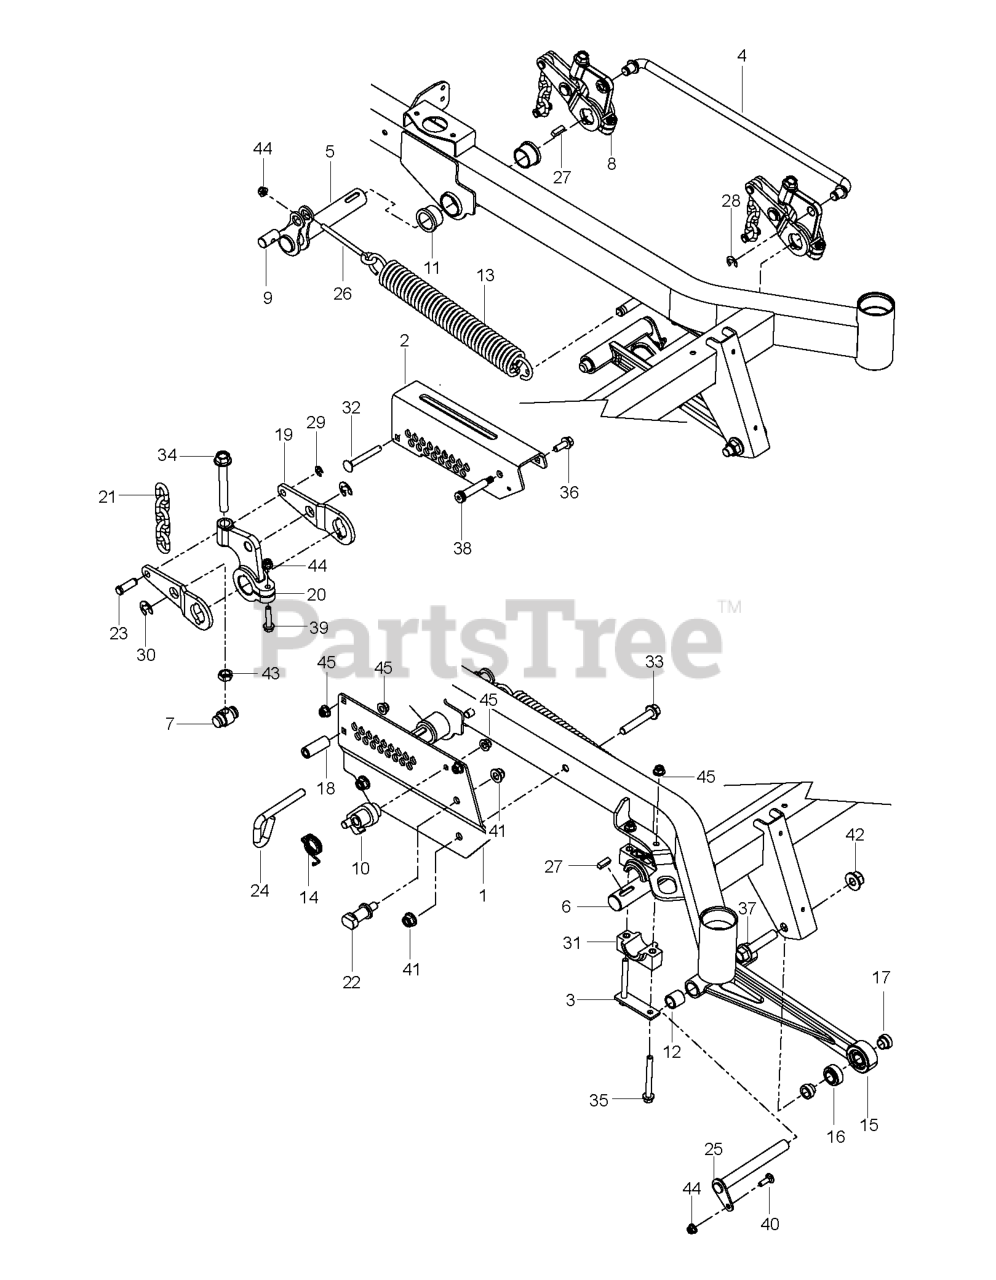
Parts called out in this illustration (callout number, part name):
1	PLATE INNER HEIGHT SNAPPER RED
2	PLATE OUTER HEIGHT SNAPPER RED
3	PLATE, PILLOW BLACK
4	ROD, LIFT
5	SHAFT, RR LIFT
6	SHAFT, LIFT, FT
7	SHAFT, LIFT TRUNION WSL
8	ASSEMBLY, DECK LIFT CRANK
9	PIVOT, SPRING
10	LATCH, TRANSPORT WLDMT
11	BUSHING, FLANGE 1.25 X 1.0
12	BUSHING, SLEEVE 3/4 X 1.0
13	SPRING, EXTENSION
14	SPRING, TORSION
15	ASSEMBLY, STRUT
16	BALL JOINT, 3/4" SWIVEL
17	SPACER, STRUT
18	SPACER, HEIGHT PLATE
20	ARM, CAST LIFT
21	LIFT CHAIN
22	GUIDE, HEIGHT BAR
23	PIN, 7/16 CLEVIS
24	PIN, HEIGHT
25	PIN, STRUT
26	EYE BOLT 4.5`
27	KEY, 5/16 SQ X 1.0
28	E-RING 5/8
29	RING, E, 7/16
30	E RING 3/4
31	BLOCK, PILLOW
32	3/8-16 X 3` CARR BOLT
33	HFFS 1/2-13 X 3 GD 5 ZD
34	HHFS 1/2-13 X 4 GR 5
35	HHFS 3/8-16 X 3.5 GD 5 ZD
36	HHFS 3/8-16 X 1 GRD 5 ZD
37	HHFS 5/8-11 X 3.0 GD 8 ZD
38	BOLT, SHOULDER, 1/2 X 2.25
39	HHFS 5/16-18 X 1.5 GD 5
40	BOLT CRT
41	NUT, 1/2-13 HEX FLG NYLOC ZD
42	NUT 5/8-11 FLG NYLOC ZD
43	NUT 1/2 HEX JAM
44	5/16-18 NYLOC FLANGE NUT
45	NUT 3/8-16 HEX FLG NYLOC ZD
